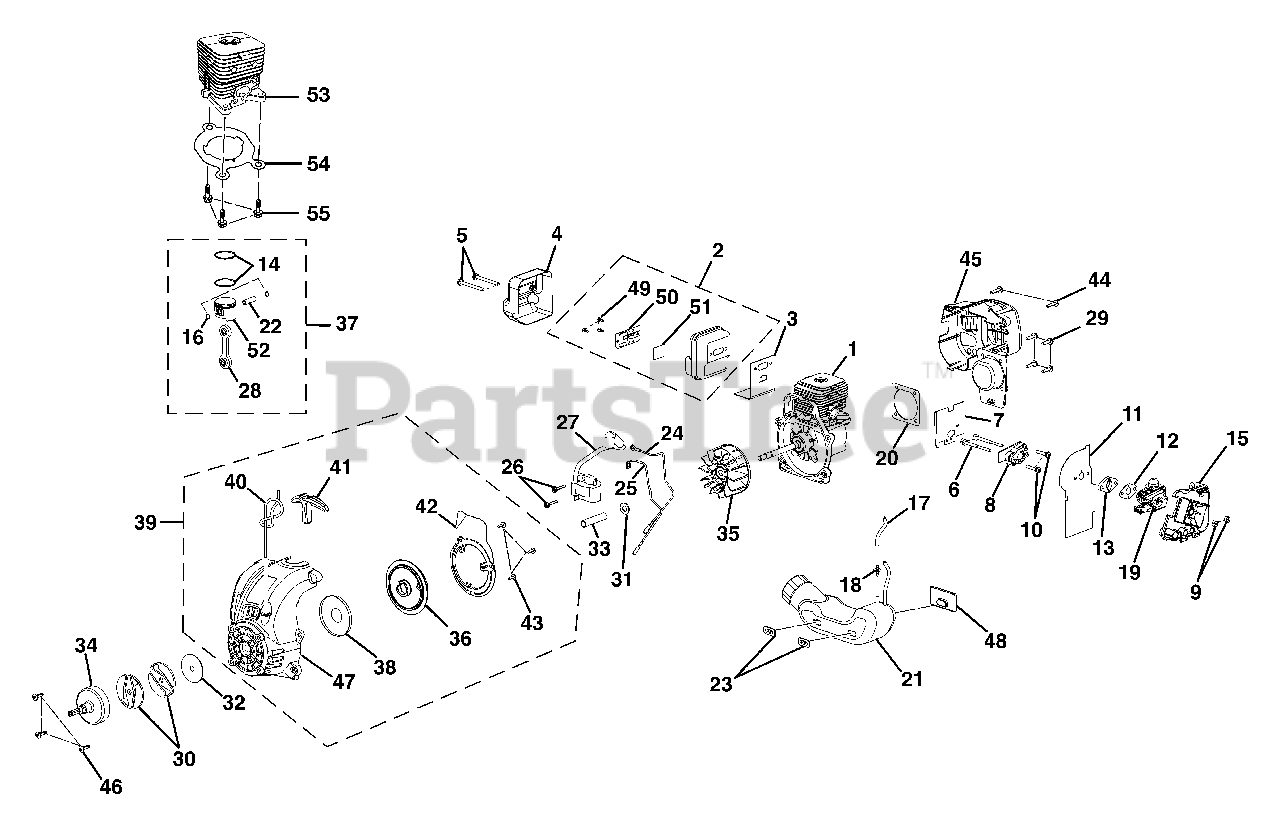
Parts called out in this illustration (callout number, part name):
1	SHORT BLOCK ASSEMBLY
2	MUFFLER ASSEMBLY
3	MUFFLER GASKET
4	HEAT SHIELD
5	SCREW (TORX HD.)
7	HEAT DAM GASKET
8	HEAT DAM
9	LOCK NUT (10-24)
10	SCREW (TORX PAN HD.)
11	CARBURETOR GASKET
12	CARBURETOR GASKET
14	PISTON RING 30CC
15	AIR FILTER BOX
16	RETAINING RING
17	TUBING, RUBBER (63.5 mm)
18	FITTING, INLINE FUEL
19	CARBURETOR, ZAMA
20	GASKET, C/C COVER
21	FUEL TANK W/CAP ASSEMBLY
22	PISTON PIN
24	LEAD W/TERMINALS
26	SCREW (8-32 X 1 in. THREAD FORMING)
27	IGNITION MODULE (W/ 3 SEC. KILL)
28	CONNECTING ROD ASSEMBLY
29	SCREW (10-24 X 3/4 in. PAN HD. TORX)
32	WASHER
34	DRUM & CONNECTOR
35	ROTOR AND PAWL ASSEMBLY
36	PULLEY ASSEMBLY
37	PISTON ASSEMBLY
38	SPRING & CONTAINER
39	COMPLETE STARTER ASSEMBLY
40	STARTER ROPE
41	STARTER GRIP
43	SCREW (8-16 X 1/2 in. THD. FORM.)
44	SCREW (10-14 X 7/8 in. THD. FORM.)
45	REAR HOUSING
46	SCREW (ST-155)
47	STARTER HOUSING W/EYELET
48	RUBBER BUMPER
49	SCREW (6-20 X 1/4 in. TRI-LOBULAR)
50	OUTLET TUBE
52	PISTON W/PINS
53	CYLINDER
54	CYLINDER GASKET
55	SCREW (12-24 X 5/8 in.)
